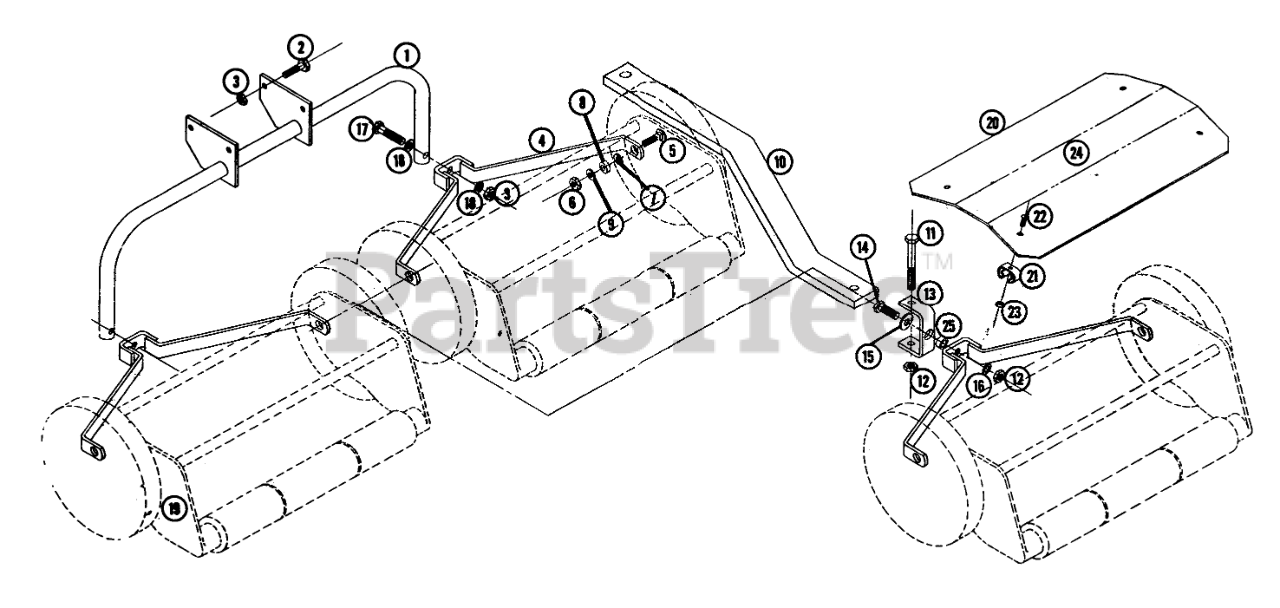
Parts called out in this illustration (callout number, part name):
6	Nut, 5/16-18
7	Lockwasher, 5/16 In.
9	Washer
11	Hex Hd. Cap Screw 1/2-13 x 3 1/4
12	Nut, 1/2-13
15	Washer-Flat
17	Bolt 3/8-16 x 2 1/4
18	Washer
21	Clamp
24	Decal
